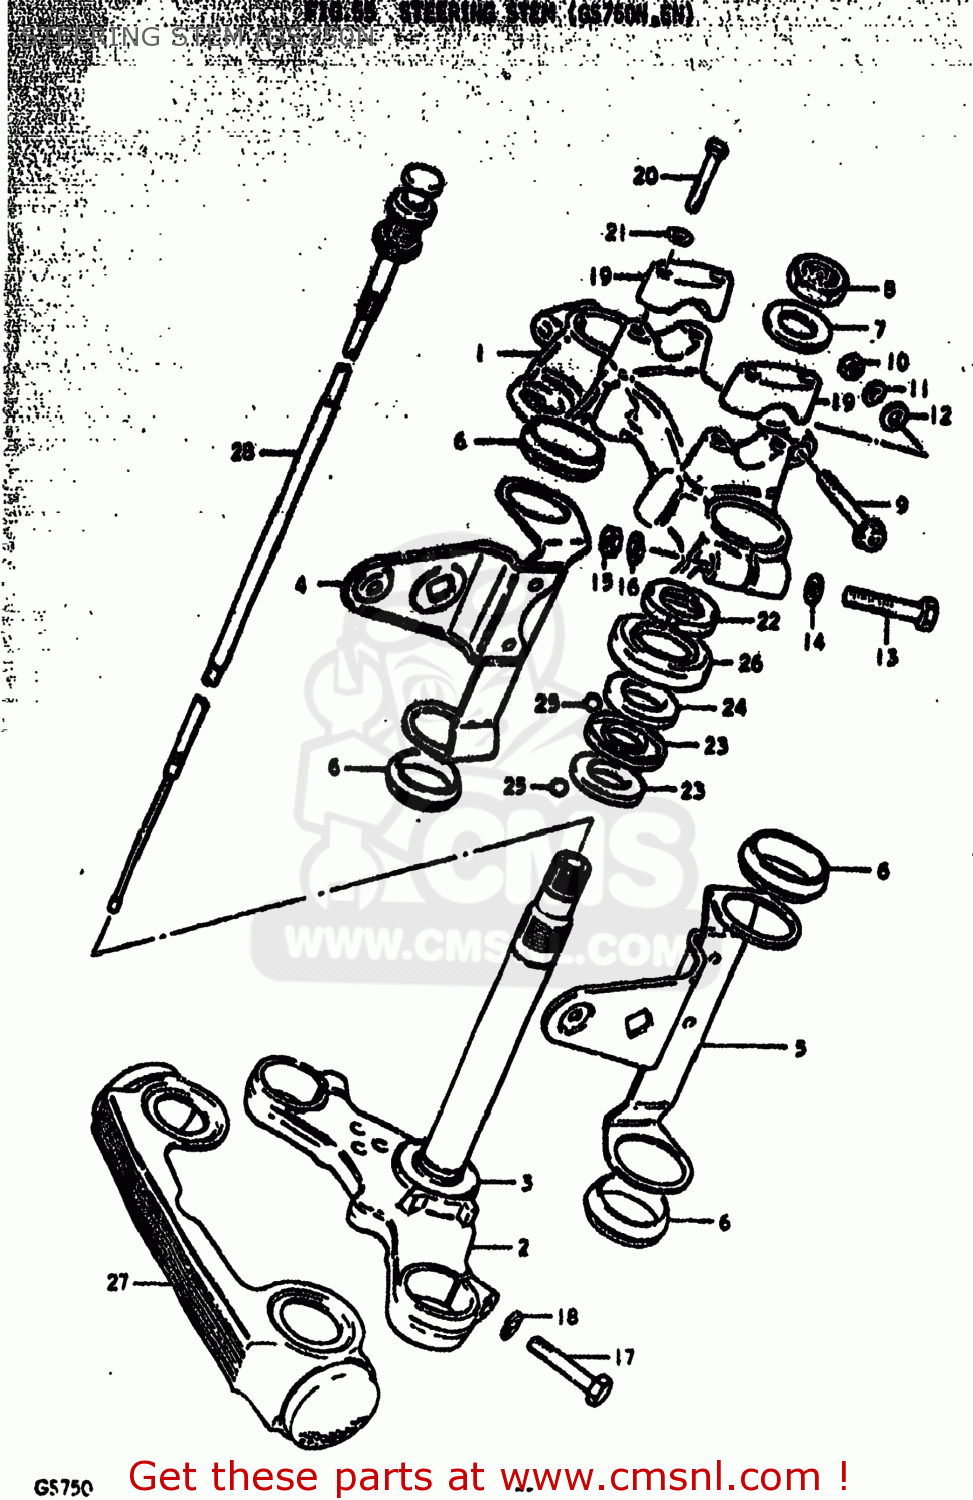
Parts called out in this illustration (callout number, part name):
1	HEAD,STEERING STEM
2	STEM,STEERING
3	RACE,STEERING OUTER LWR
4	BRACKET,HEADLAMP,RIGHT
5	BRACKET,HEADLAMP,LEFT
6	CUSHION,HEADLAMP BRACKET
7	WASHER
8	NUT,FR FORK UPR BRACKET
9	BOLT
10	NUT
11	LOCK WASHER
12	WASHER
13	BOLT 10X55
15	NUT
16	LOCK WASHER
17	BOLT 10X40
18	LOCK WASHER
19	HOLDER,HANDLE UPR
20	BOLT
21	LOCK WASHER
22	NUT,STEERING STEM(25X44X10)
23	LACE,STEERING INNER LWR
24	LACE,STEERING OUTER UPR
25	BALL
26	DUST SEAL,STEERING UPR
27	COVER,FR FORK
28	CABLE ASSEMBLY,STARTER
